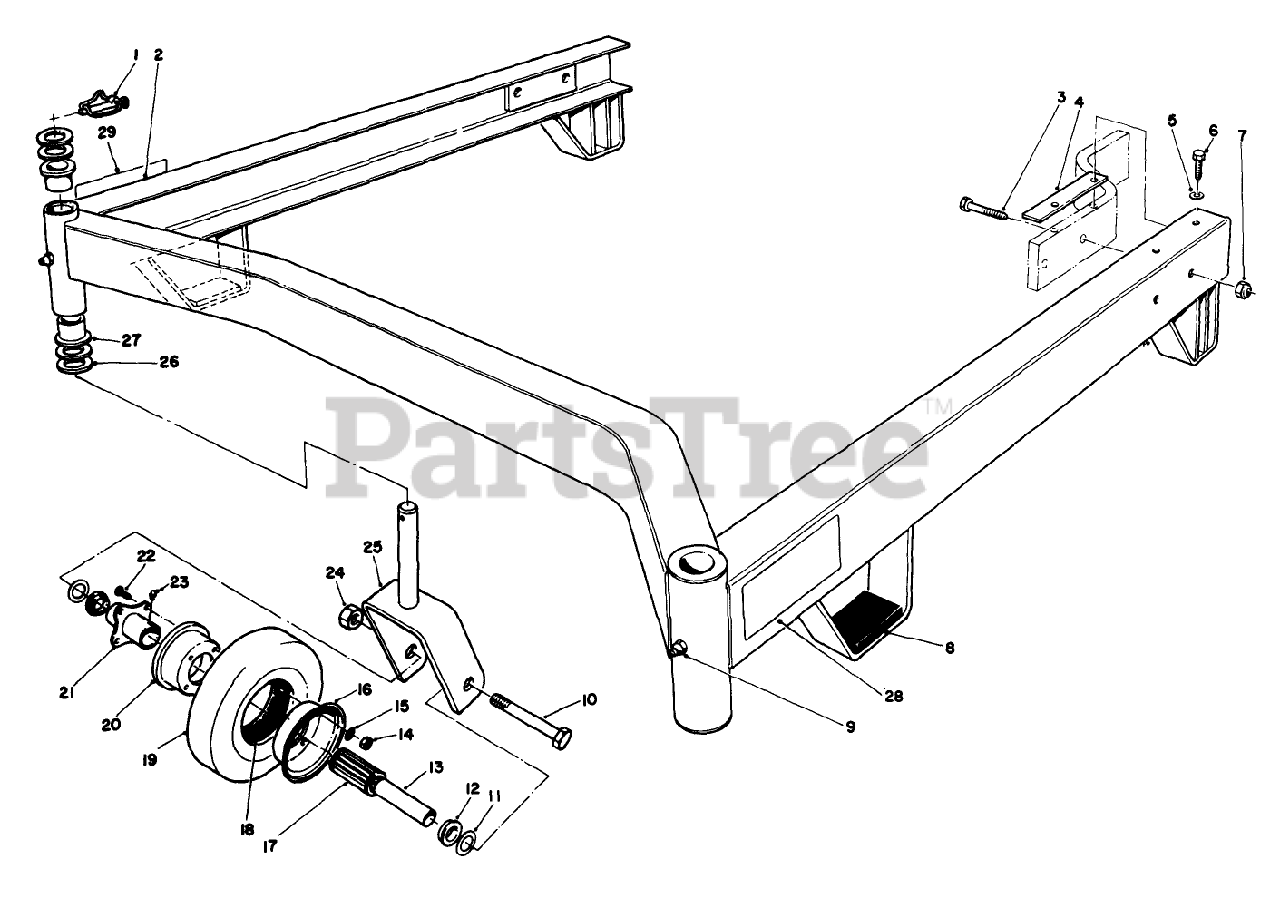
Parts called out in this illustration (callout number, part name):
1	PIN-LYNCH
2	Suspension Assembly (Incl. Ref. #9 & 27)
3	SCREW-HH
4	SHIM-CARRIER
5	WASHER-FLAT
6	SCREW W/PATCH
7	NUT-LOCK, CONE
8	Pad-Rubber
9	FITTING-GREASE
10	SCREW-HH
11	WASHER-FLAT
12	Bushing
13	SPANNER-TIRE
14	NUT-HEX
15	WASHER-LOCK
16	MALE WHEEL HALF
17	BEARING-ROLLER
18	TUBE-INNER (W/VALVE)
20	FEMALE WHEEL HALF
21	HUB-CENTER
22	WHEEL BOLT
23	FITTING-GREASE
24	NUT-HEX
25	Castor Fork
26	WASHER-THRUST
27	Bushing
28	DECAL-HOC, RH
29	DECAL-HOC, LH
